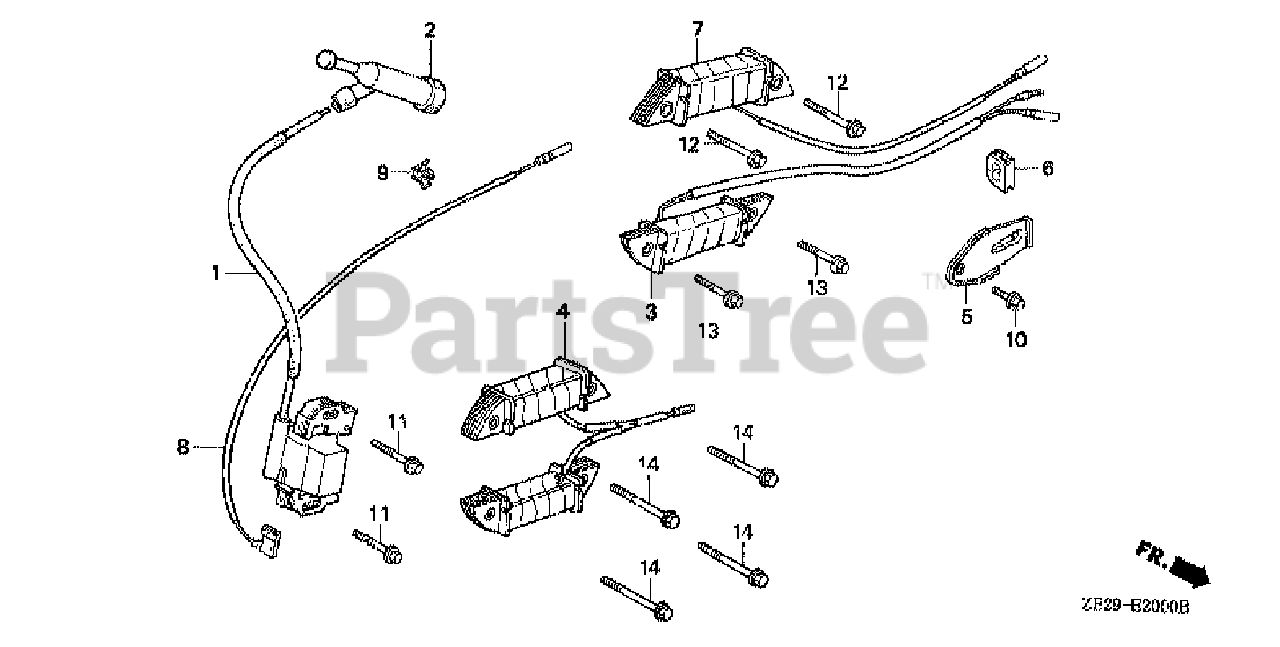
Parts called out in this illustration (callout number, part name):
1	COIL ASSY., IGNITION
2	CAP ASSY., NOISE SUPPRESSOR
6	GROMMET, WIRE
8	WIRE, STOP SWITCH (370MM)
11	BOLT, FLANGE (6X28)
